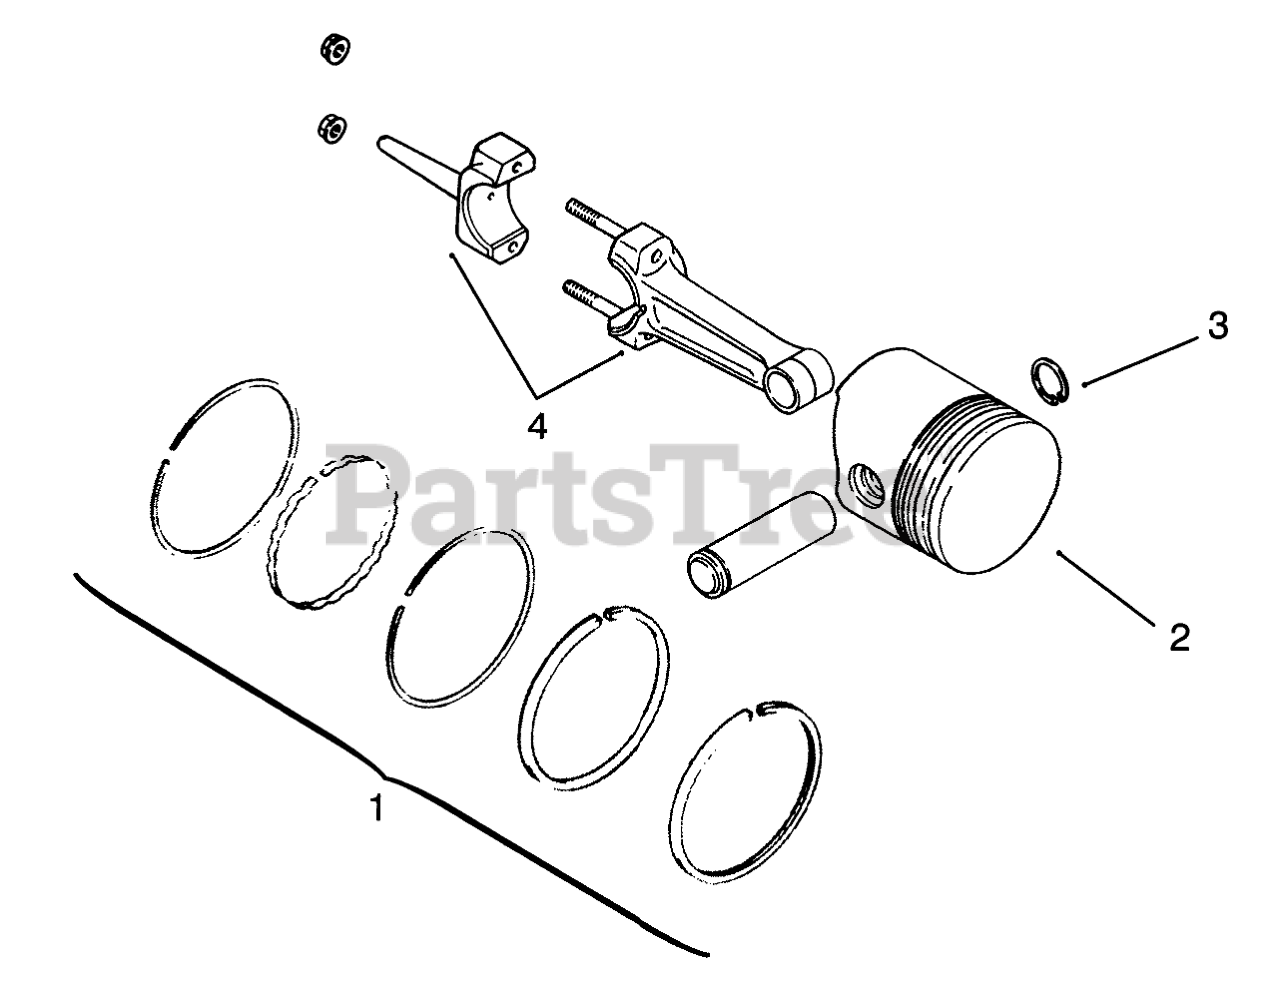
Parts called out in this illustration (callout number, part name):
1	Set-Ring, Std. &.003
2	Piston w/Ring Set Std.
3	Piston Pin Retainer
4	Rod-Connecting Std.
